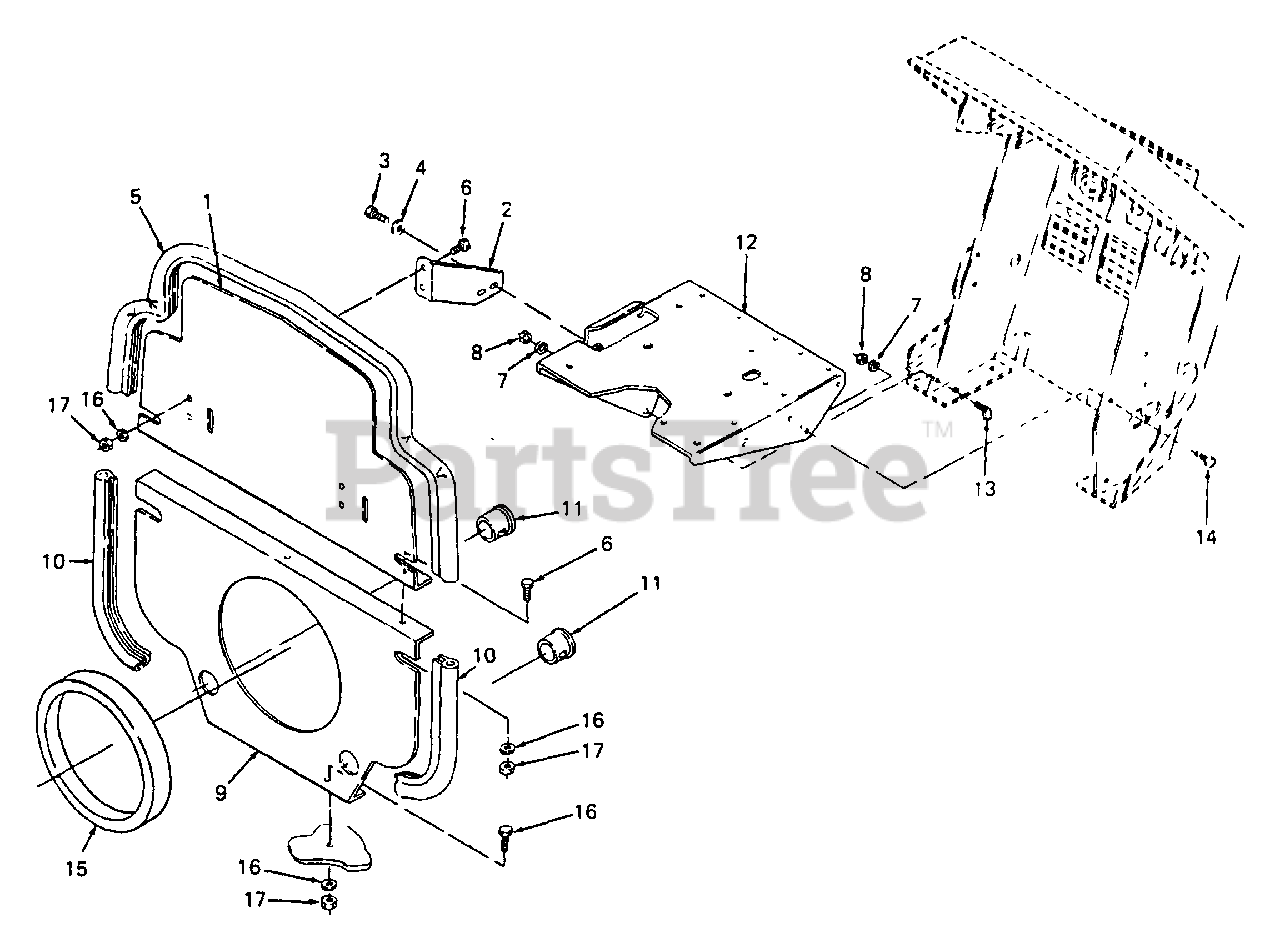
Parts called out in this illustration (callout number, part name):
3	Screw, Hex Cap, 5/16-18 X.50 Lg GR5
4	Washer, Bell, .345 x .88 x .060 Thk
5	Seal, Bulkhead, 36" Lg
6	Screw, Hex Cap, 1/4-20 x .50 Lg GR5
7	Washer, Lock, 1/4
8	Nut, Hex, 1/4-20 GR5
9	Bulkhead, Lower
10	Seal, Bulkhead, 10" Lg
11	Bushing, Snap, 7/8 ID
12	Tray Assy, Battery
13	Bolt, J-Type, 1/4-20
14	Screw, Hex Cap, 1/4-20 x .62 Lg GR5
15	Ring, Foam Sealing
16	Washer, Bell, .265 x .75 x .062 Thk
17	Nut, Hex Top Lock, 1/4-20
